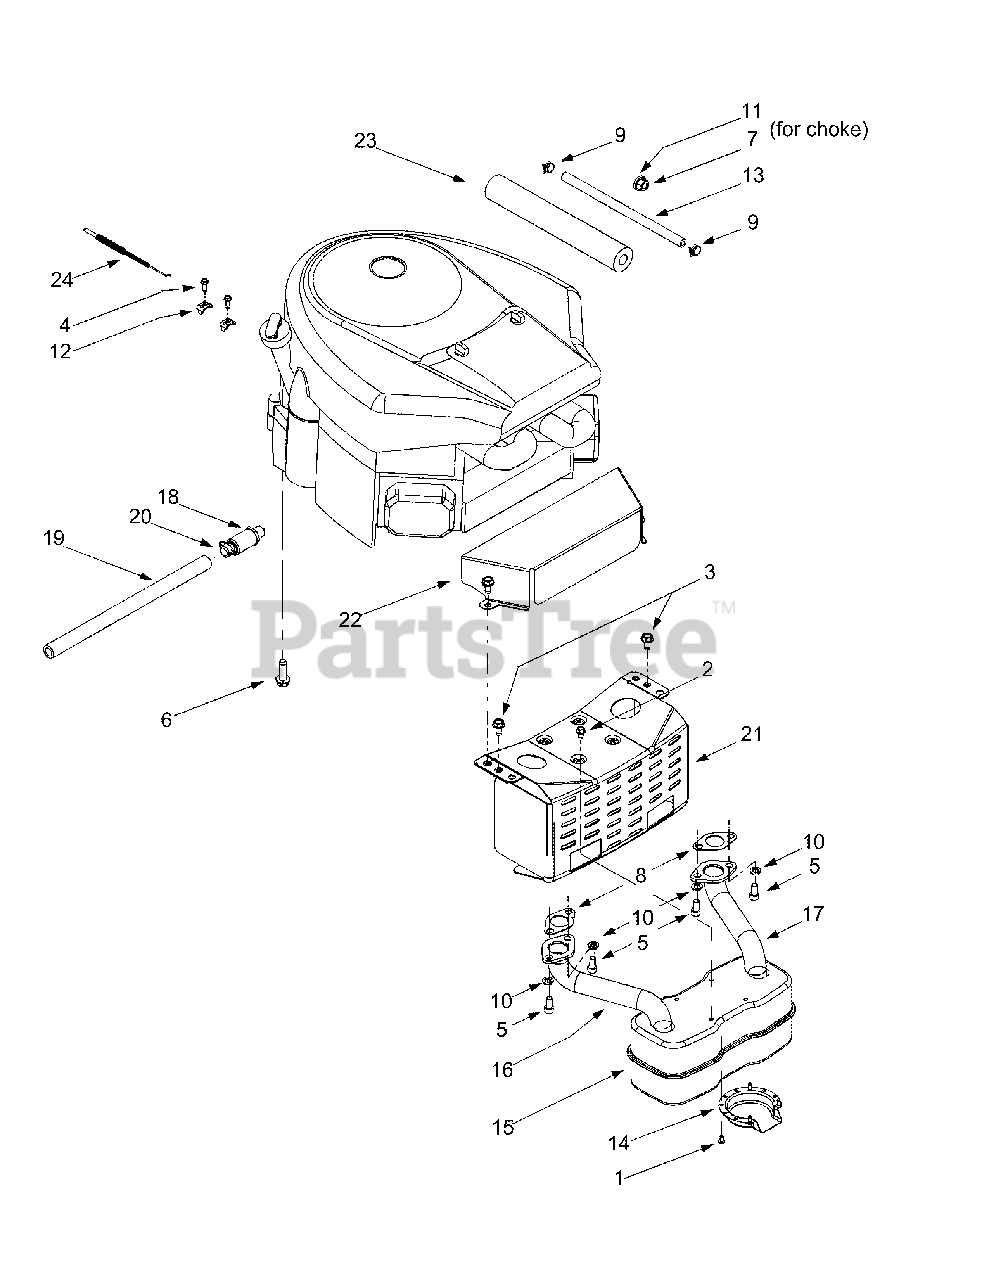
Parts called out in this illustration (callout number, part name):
1	Self-tapping Screw, #8-18 x .5
2	Self-tapping Screw, 1/4-20 x .5
3	AB Screw, 5/16-12 x .75
4	Screw, #10-32 x .625
5	Socket Cap Screw, 5/16-18 x .625
6	Self-tapping Screw, 3/8-16 x 1.25
7	Hex Nut, 3/8-16
8	Exhaust Gasket
9	Hose Clamp
10	Lock Washer, 5/16
11	Flat Washer
12	Casing Clamp
13	Fuel Line Hose
14	Muffler Deflector
15	Muffler, Twin Inlet
16	RH Exhaust Pipe
17	LH Exhaust Pipe
18	Oil Drain Valve
19	Oil Drain Hose
20	Oil Drain Cap
21	Muffler Heat Shield
22	Engine Heat Shield
23	Foam (fits over fuel line)
24	Throttle Cable
